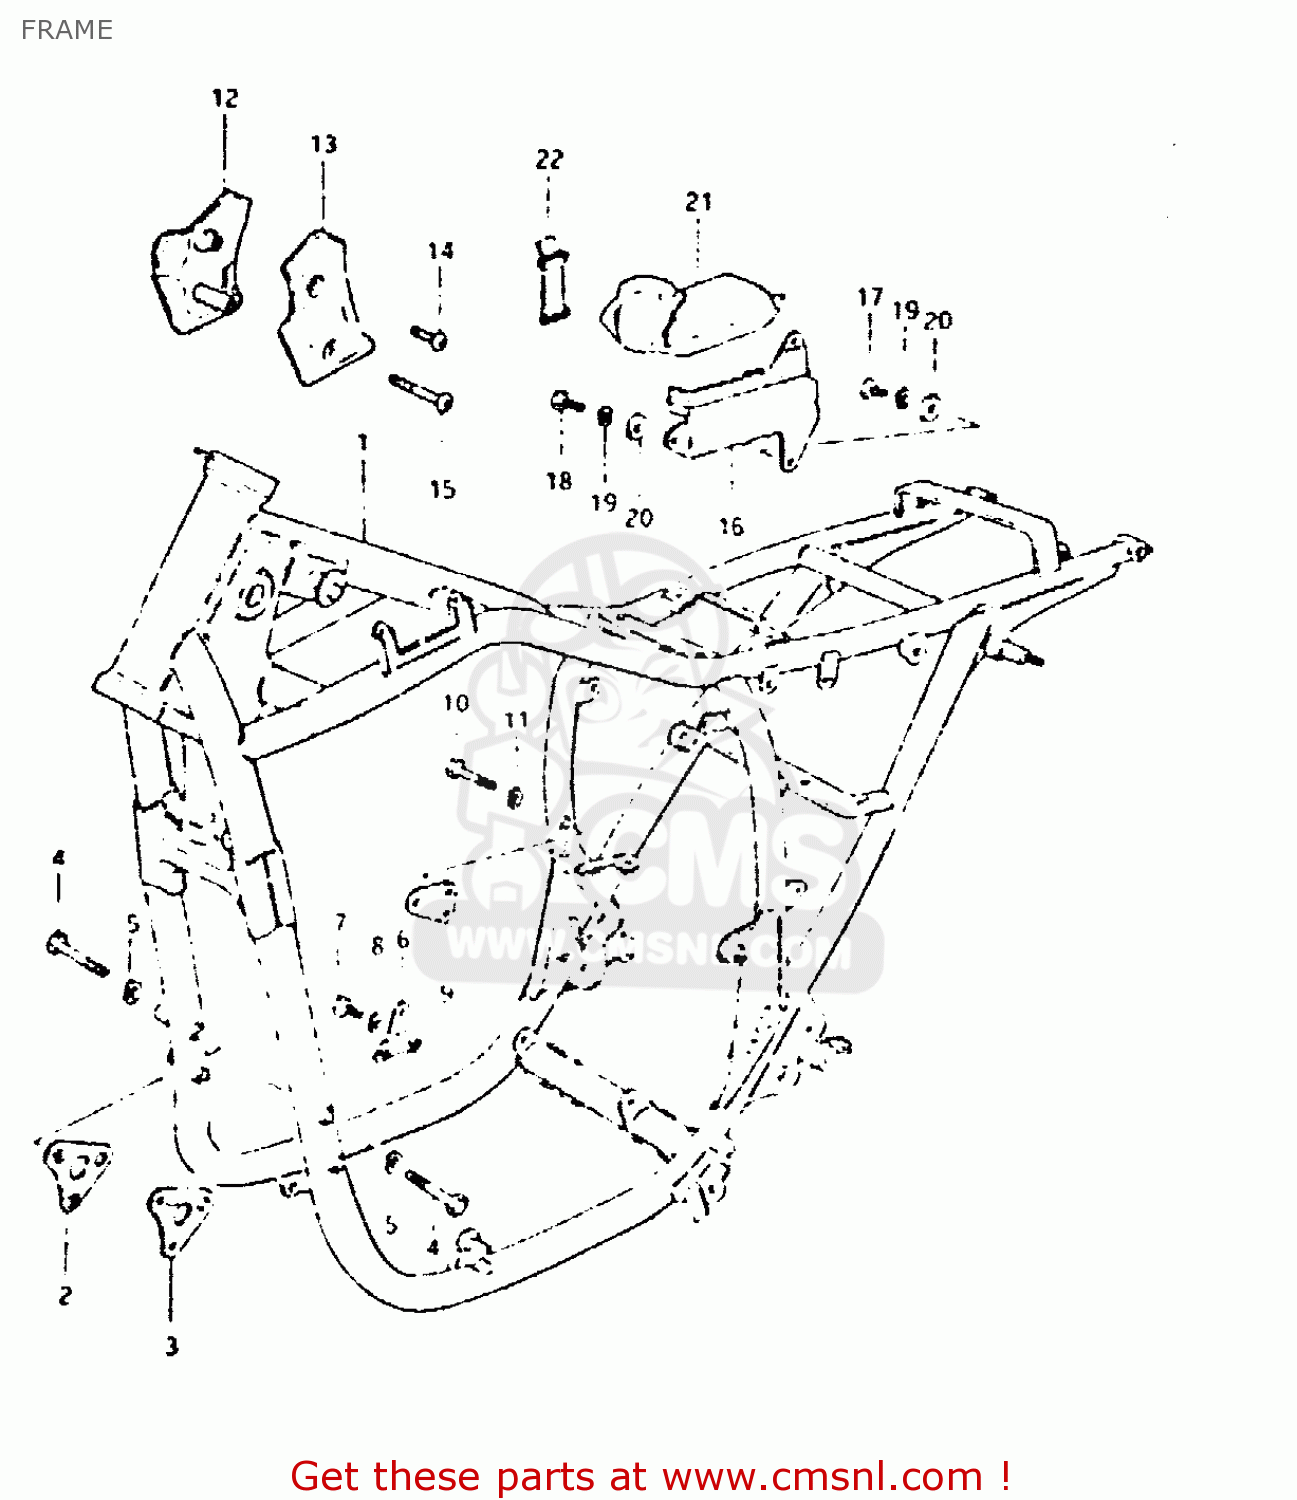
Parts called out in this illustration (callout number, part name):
1	FRAME
2	PLATE,ENGINE MOUNTING
3	PLATE,ENGINE MOUNTING
4	BOLT
5	LOCK WASHER
6	PLATE,ENGINE MOUNTING
7	BOLT
8	LOCK WASHER
9	PLATE,ENGINE MOUNTING
10	BOLT 8X45
11	LOCK WASHER
12	COVER,FRAME HEAD,RIGHT
13	COVER,FRAME HEAD,LEFT
14	(5X20) CROSS SCREW
15	SCREW, LOWER
16	HOLDER,TOOL
17	SCREW 6X12
18	SCREW
19	LOCK WASHER
20	WASHER
21	TOOL SET
22	BAND
